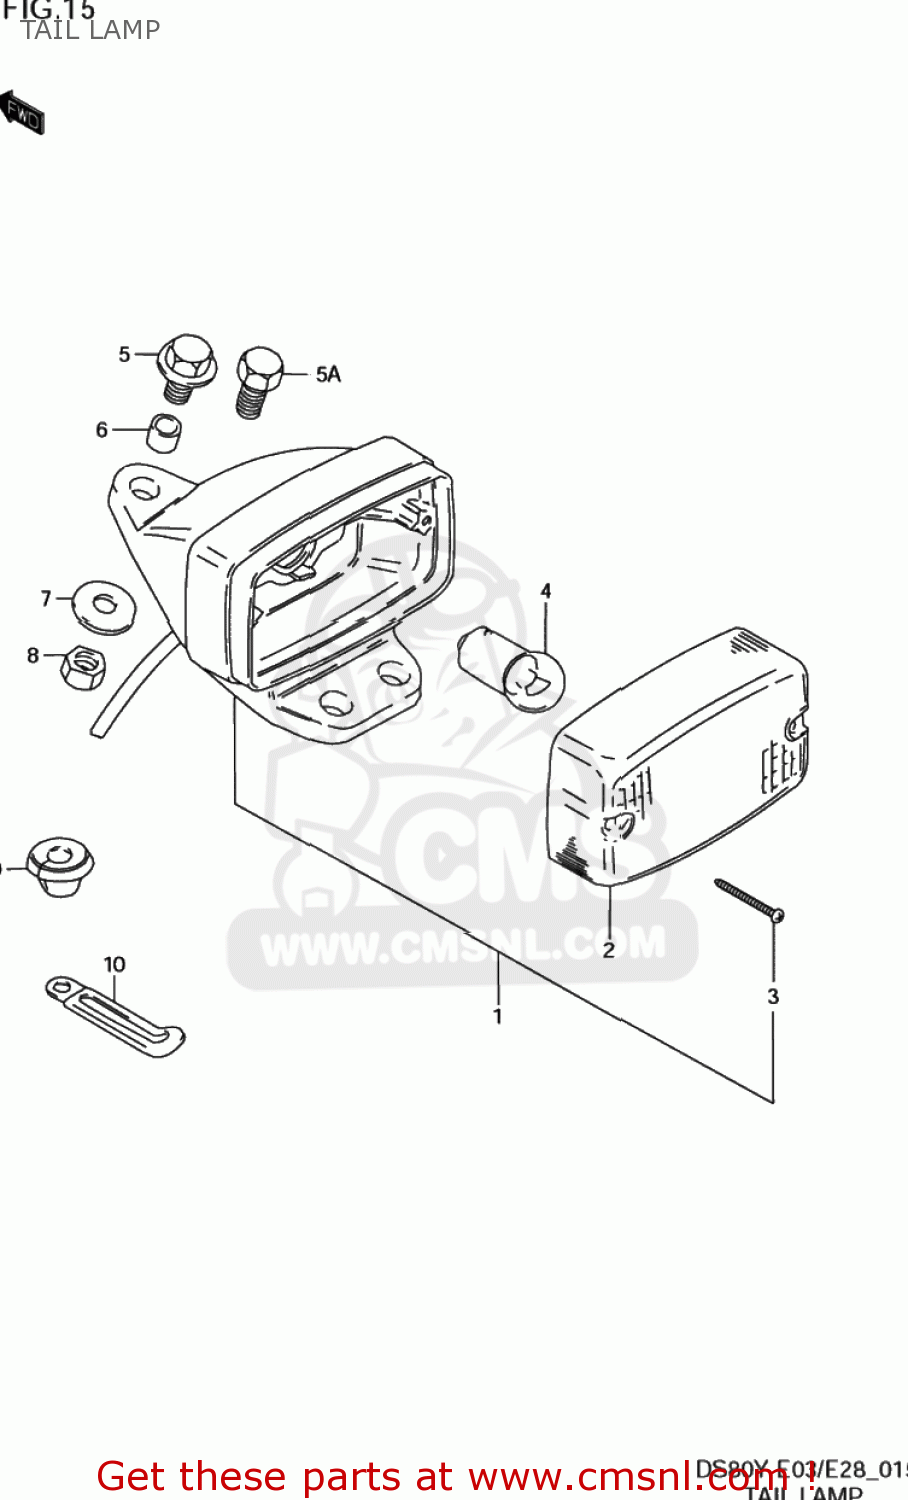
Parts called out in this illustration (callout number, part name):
1	LAMP ASSY,TAIL
2	LENS
3	SCREW
4	BULB(6V5W,TOKAI DENSO)
5	BOLT 6X20
5A	BOLT
6	SPACER(6.5X9X9)
7	WASHER(6.5X20X1.2)
8	NUT 6MM
9	GROMMET
10	CLAMP(L:65)
